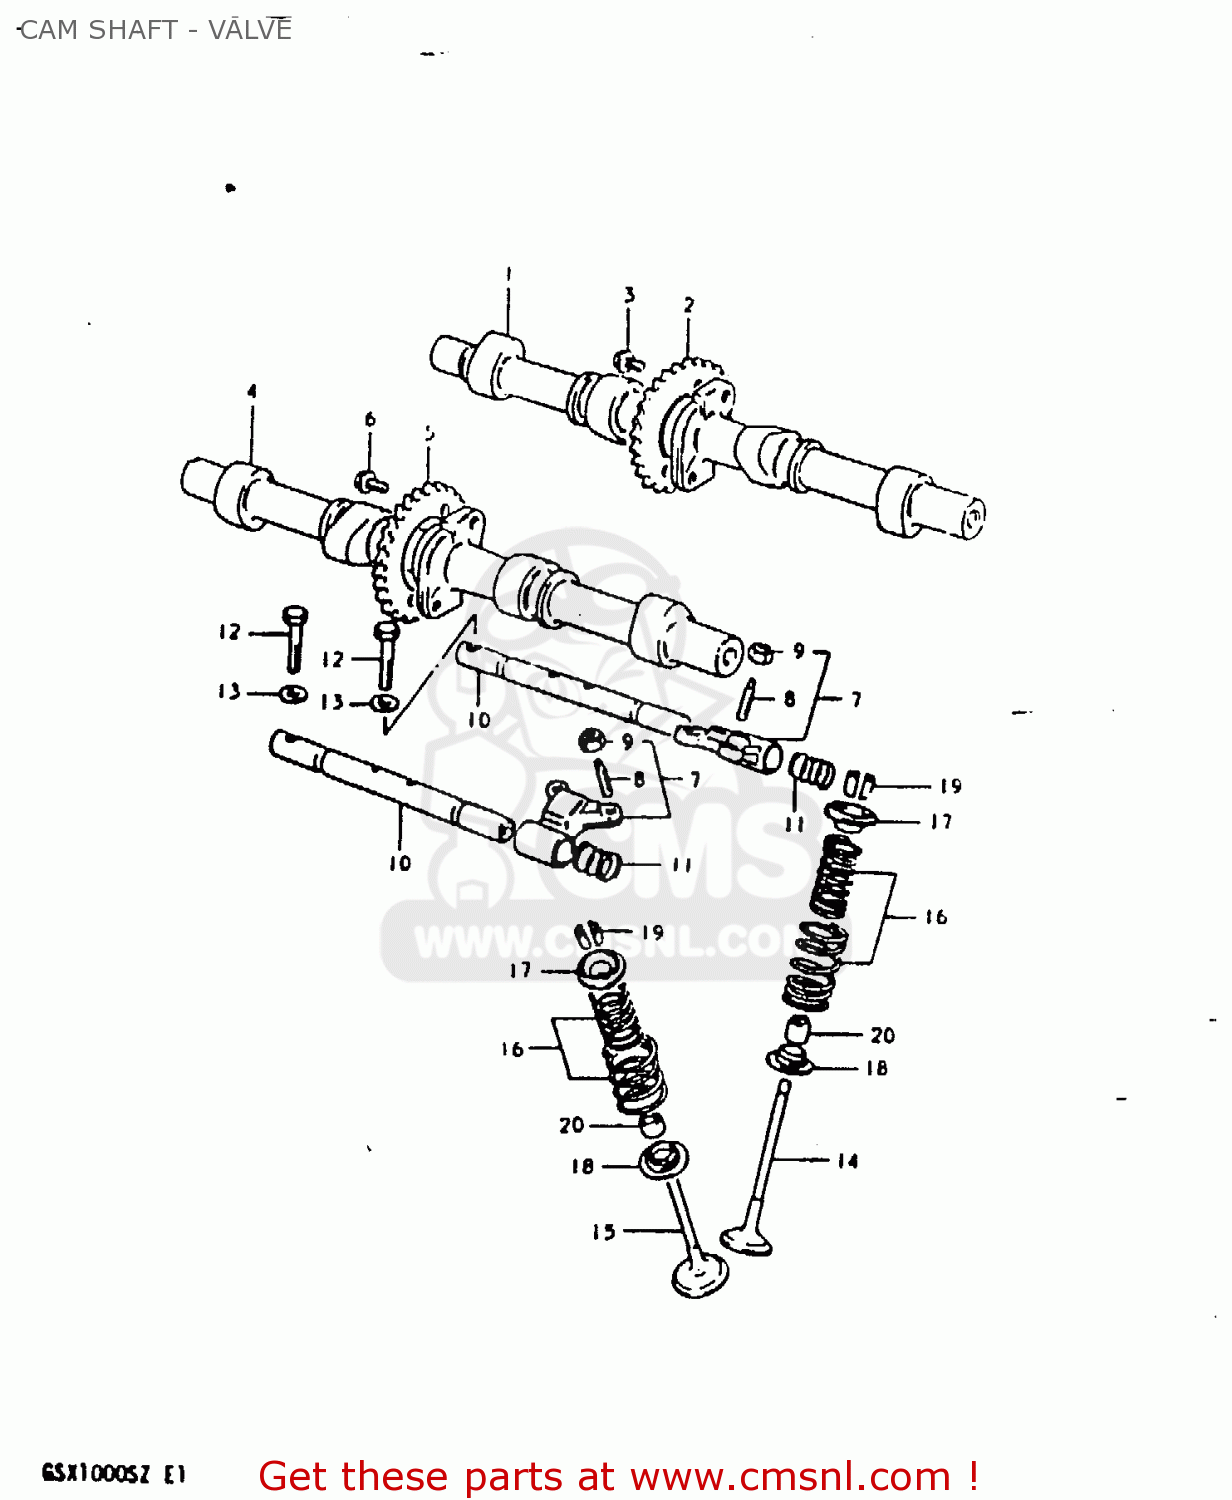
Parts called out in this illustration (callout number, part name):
1	CAMSHAFT
2	SPROCKET, INTAKE (NT:30)
3	BOLT(7X11)
4	CAMSHAFT,EXHAUST
5	SPROCKET,EXHAUST CAMSHAFT
6	BOLT(7X11)
7	ARM,VALVE ROCKER
8	SCREW,TAPPET ADJUSTING
9	NUT,ADJUSTING
10	SHAFT,VALVE ROCKER
11	SPRING
12	BOLT
13	WASHER
14	VALVE,INTAKE
15	VALVE,EXHAUST
16	SPRING SET,VALVE
17	RETAINER,VALVE SPRING
18	SEAT,VALVE SPRING
19	COTTER VALVE
20	OIL SEAL
